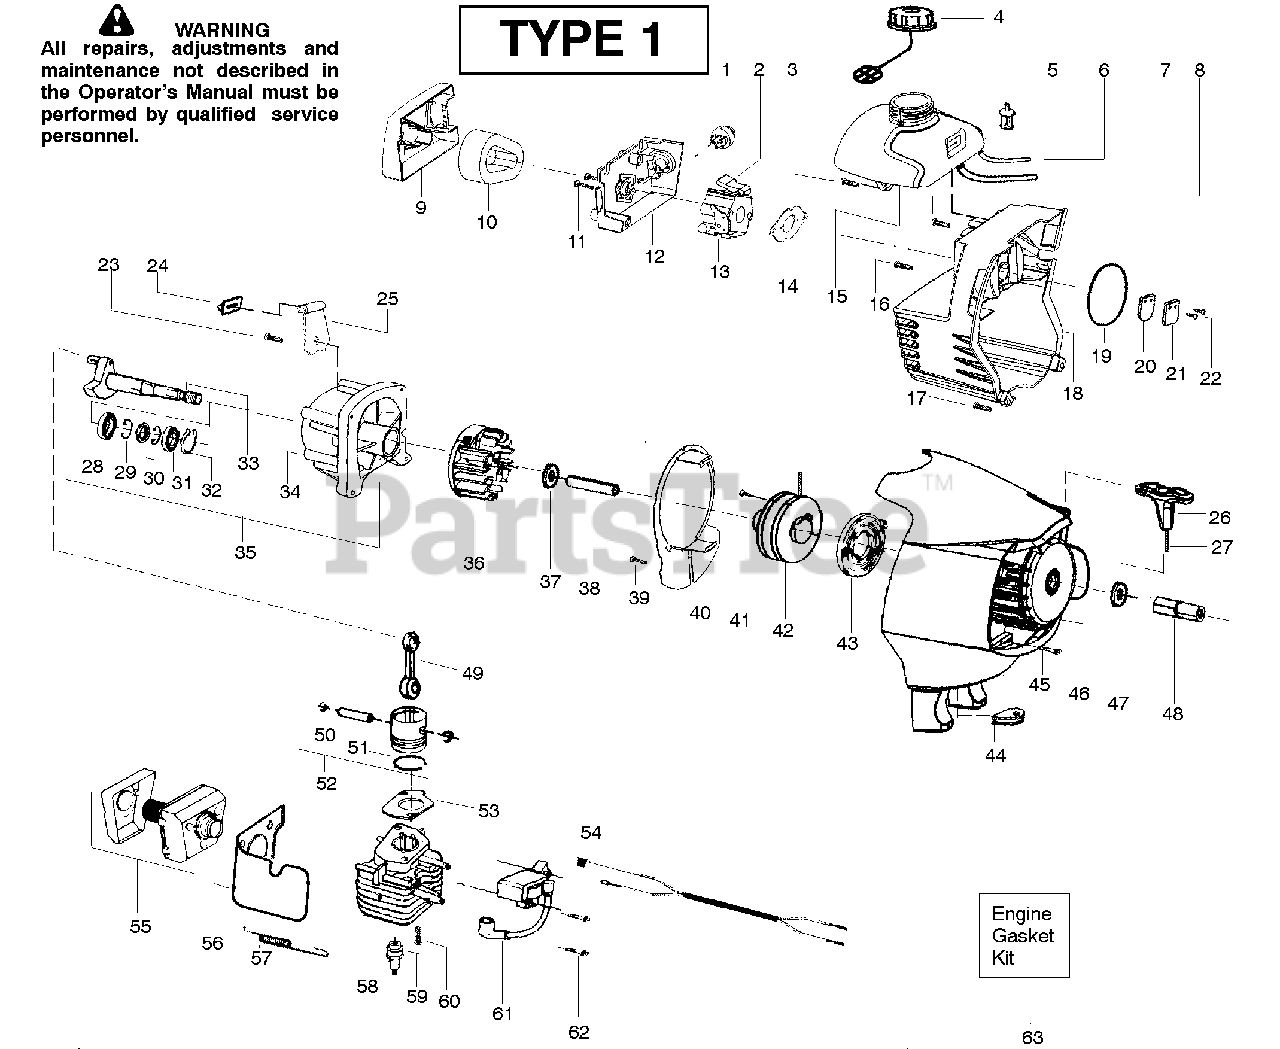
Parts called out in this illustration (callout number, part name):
2	Kit-Choke Lever
4	Cap-Fuel w/ret.
5	Assy-Fuel pickup
6	Kit-Fuel line
7	Kit-Fuel/Purge line
9	Cover-Air box
13	Assy-Carb(WT628)
14	Gasket-Carb.(kit)
15	Assy-Fuel Tank
16	Screw-Crankcase
19	O-ring-Shroud (kit)
22	Screw-Reed stop
23	Screw-Retainer
24	Isolator-Tank
26	Handle-Starter
27	Kit-Rope
28	Bearing-Inner
31	Bearing-Outer
32	Ret.-Crankshaft
33	Assy-Crankshaft
34	Assy-Crankcase
35	Assy-C'case/C'shaft
36	Kit-Flywheel Assy.
40	Plate-Baffle
42	Kit-Pulley
43	Spring-Starter
45	Screw-F/hsg.
46	Assy.-Fan Housing
48	Coupling-Drive
49	Assy-Conn. Rod
50	Ret.-Piston pin
52	Kit-Piston
53	Gasket-Cylinder(kit)
54	Assy-Leadwire
57	Spring-Muffler
59	Plug-Spark(RCJ-6Y)
60	Bolt-Cyl. 1/4-20"
61	Module-Ignition
63	Kit-Gasket
